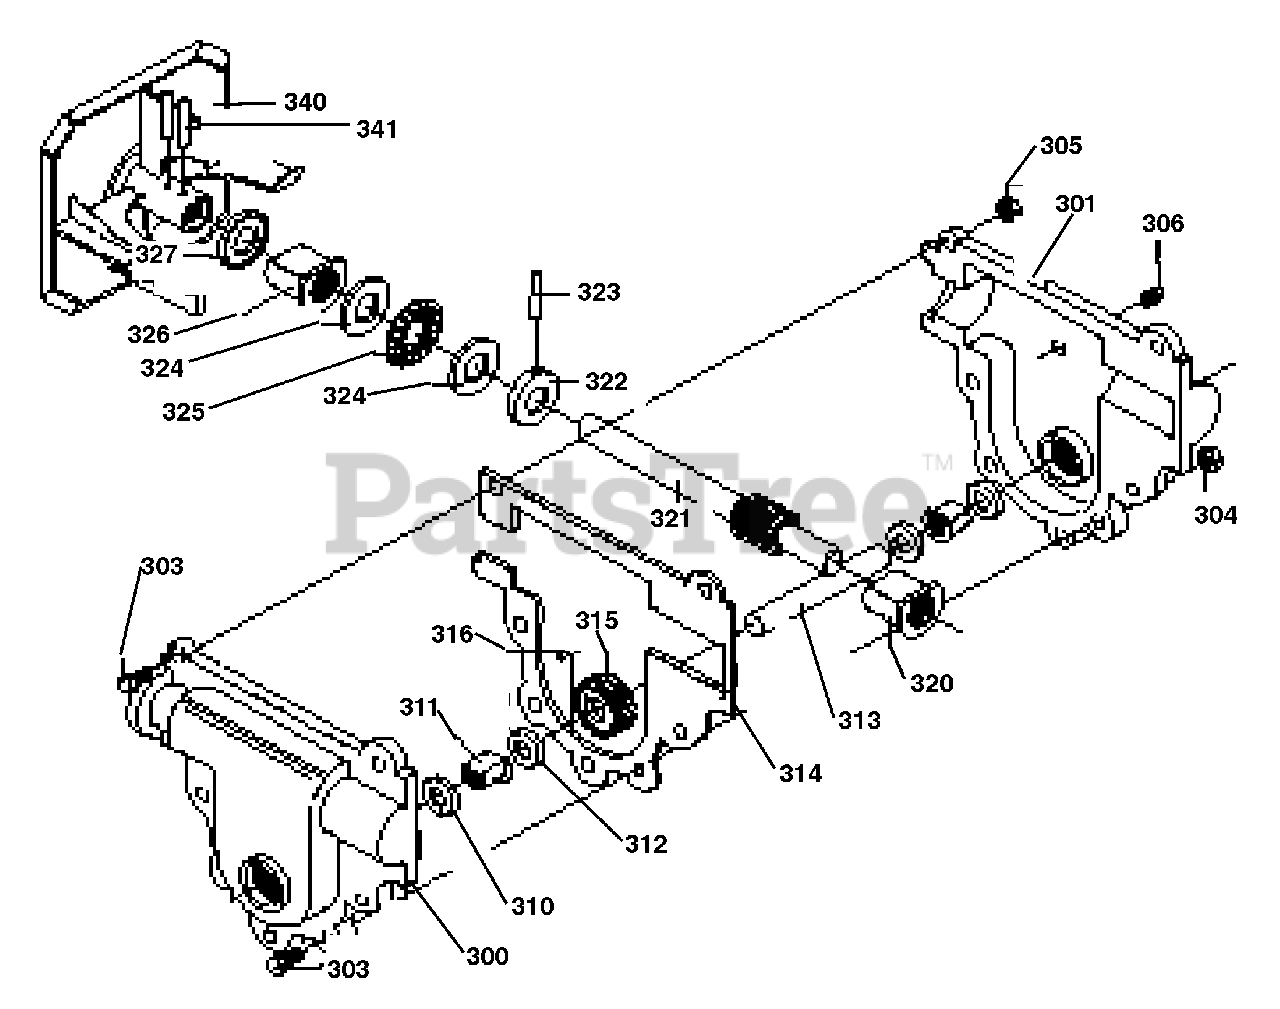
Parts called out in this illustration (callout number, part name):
300	Gear Case, RH
301	Gear Case, LH
303	Screw, 1/4-20 x .75
304	Nut, 1/4-20
305	Nut, 1/4-20 Hexkeps
306	Screw, 3/8-16 x .50
311	Bearing, Flange
312	Flatwasher, .752 x 1.24 x .093
313	Shaft, Auger Output
314	Gasket, Gear Case
315	Gear, Worm
316	Key, Woodruff
320	Bearing, Flange
321	Shaft, Worm Imp Input
322	Collar, Thrust .753 x 1.24 x .50
323	Pin, Spring
324	Flatwasher, .752 x 1.24 x .093
325	Bearing, Roll
326	Bearing, Flange
340	Impel, Assy
341	Spring Pin
